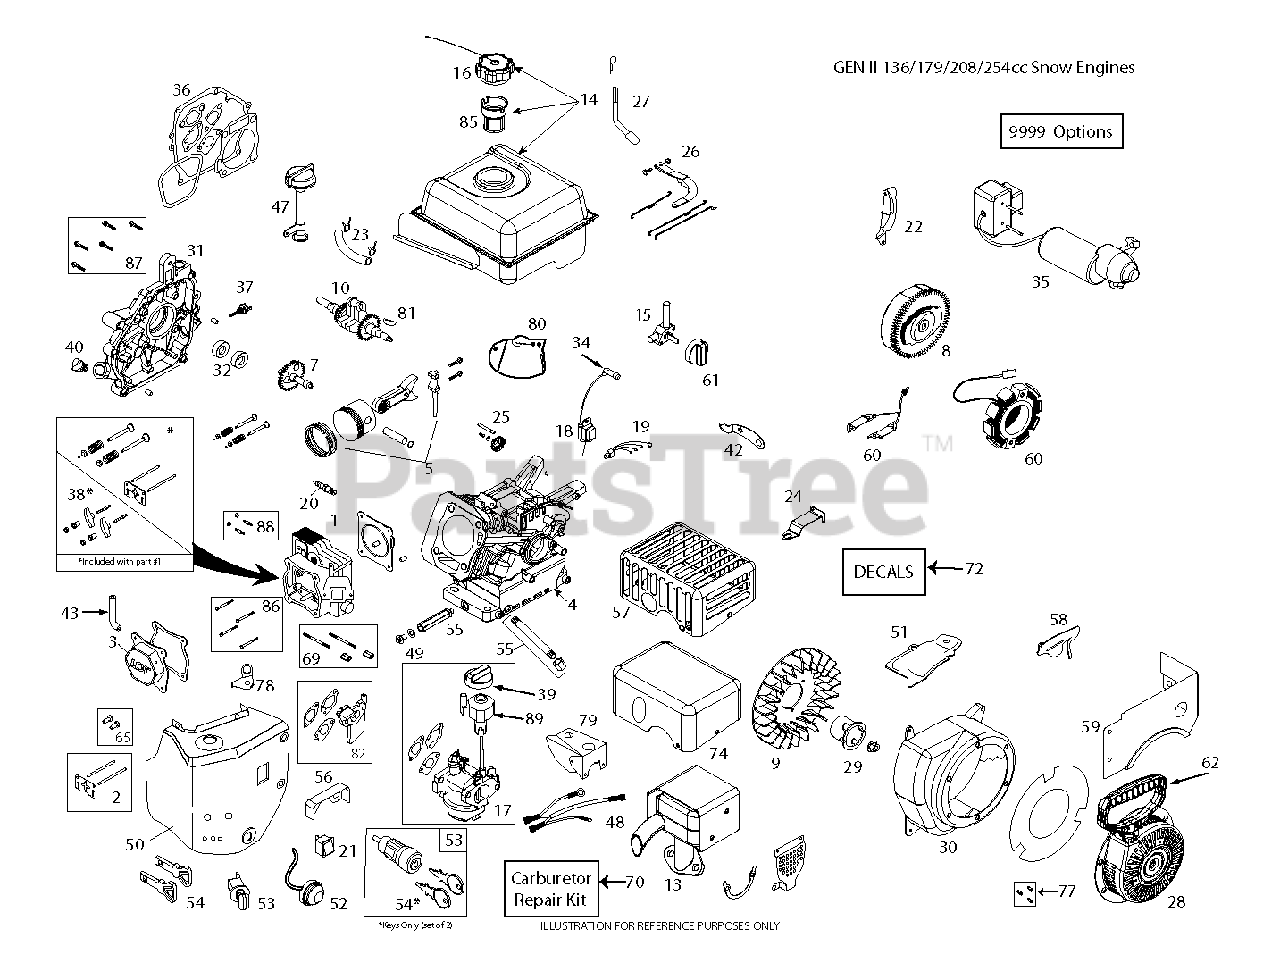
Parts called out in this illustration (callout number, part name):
1	Cylinder Head Assembly with Gasket, 254
2	KIT.PUSH.ROD.&.PLATE.W/VC.GASK
3	COVER.VALVE.W/GASKET.254CC
5	PISTON.&.ROD ASSEM.254CC
7	CAMSHAFT.MCR.W/GASKET.254CC
8	FLYWHEEL.ELEC.STRT.(8.MAGNETS)
9	KIT.COOLNG.FAN.SERV(SK208-4000
13	MUFFLER.ASSEM.GEN2.SNOW.254CC
15	FUEL.PETCOCK.SNOW(SKSN4900)
16	FUEL CAP OVERSIZED CLICK STYLE
17	Carburetor, LCT 254 with Idle-Down
18	COIL.ING.CDI.HI TEMP.SKSNO416.
20	PLUG.SPARK.PLAT.SKSN2404.1
21	SWITCH.ON/OFF(SKSN-0403)
22	SHIELD.FLYWHEEL.ELEC.STRT.208C
23	FUEL HOSE KIT
24	BRACKET.SPEED.CNTRL.FIXED.254C
25	GOVENOR.GEARS ASM(SK2082900)
26	KIT.GOVERNOR.ARM.&.LINK.254CC
27	KIT.GOVERNOR.CRANK(SK208-3100)
28	RECOIL.STRT.ROUND(BLK) SNOW
29	STRTER.CUP(NON-SLOT)SKSN0601.2
30	BLOWER HOUSING.LCT.208.ES W/OIL
31	CRANKCASE.CVR.PRESS.IN.HI-OIL.
32	Oil Seal Kit, 2 Pieces 254CC
34	SPARK.PLUG.BOOT.SNW,SKSN4691.1
35	ELEC.START.GEN2.SKSN0400.2
36	KIT.ENGINE.GASKET.254CC
38	KIT.ROCKER.ARM.W/GASKET.254CC
39	CHOKE.KNOW.SNOW(SKSN4500)
43	TUBE.BREATHER.LCT.208
47	High Oil Fill Tube Assembly
48	WIRE.HARNESS.SNOW
49	KIT.OIL.DRAIN.PLUG(SK2089911
52	PRIMER.BULB.WITH HOSE (SNOW)
53	SWITH.KEY.ASSEM.SNOW.SINGLE.ST
54	KEY SET(2 KEYS) SKSN0407.1
55	OIL PIPE DRAIN LCT 254
56	SHIELD.CARBURETOR.VAPOR
58	SHIELD.GOVERNOR.LINKAGE.254CC
59	FUEL TANK SKIRT SHIELD LCT 254
60	208CC 60W ALTERNATOR
61	FUEL KNOB-SNOW
62	HANDLE.RECOIL.DEL.SKSN0613.1
65	TAPPET.KIT.LCT.208CC
69	CARB.STUDS & COUPLING KIT.SNOW
70	Carburetor Repair Kit, LCT SK9900
74	Muffler Heat Shield Cover
77	Recoil Bolt Kit, LCT
79	COVER.CARBURETOR.SNOW
80	SHIELD.GOVERNOR.LINK.SNOW.254C
81	Flywheel Keys, 136/291cc 5-Pack
82	Carburetor Spacer, 208cc Lct
85	Fuel Tank Strainer, LCT 208cc
86	KIT.BOLT.CYLINDER.HEAD.(4PC)
87	KIT.BOLT.CRANKCASE.COVER.6PC
88	STUD.MUFFLER.KIT.LCT
89	Speed Knob, LCT Sksn5325.1
9999	High Altitude Jet, LCT >5000 25
